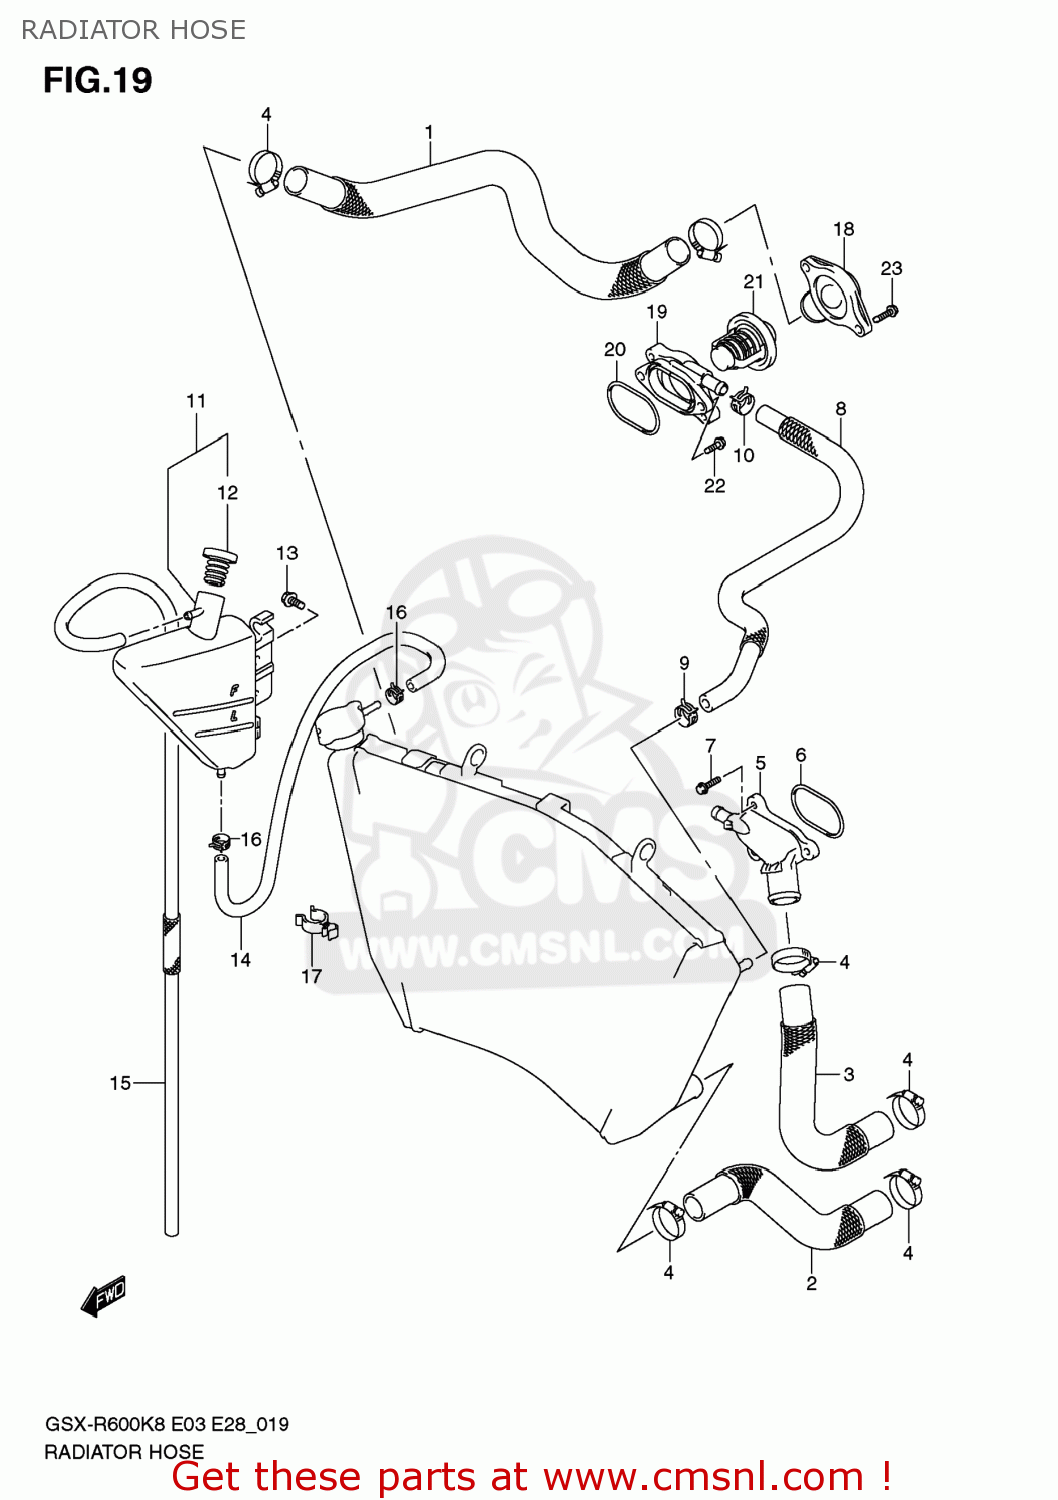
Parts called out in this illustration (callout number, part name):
1	HOSE,RADIATOR INLET
2	HOSE,RADIATOR OUTLET
3	HOSE,CYLINDER INLET
4	CLAMP
5	CONNECTOR,CYLINDER WATER INLET
6	O RING,CYL WATER CONNECTOR
7	BOLT
8	HOSE,WATER BYPASS
9	CLAMP
10	CLIP
11	TANK ASSY,RESERVOIR
12	CAP,RESERVOIR TANK
13	BOLT(6X12)
14	HOSE,RESERVOIR TANK INLET
15	HOSE,RESERVOIR TANK OVFL
16	CLIP
17	CLAMP(L:45)
18	COVER,THERMOSTAT
19	CONNECTOR,THERMOSTAT
20	O RING,THERMOSTAT CONNECTOR
21	THERMOSTAT,WATER 82 DEG
22	BOLT
23	BOLT
